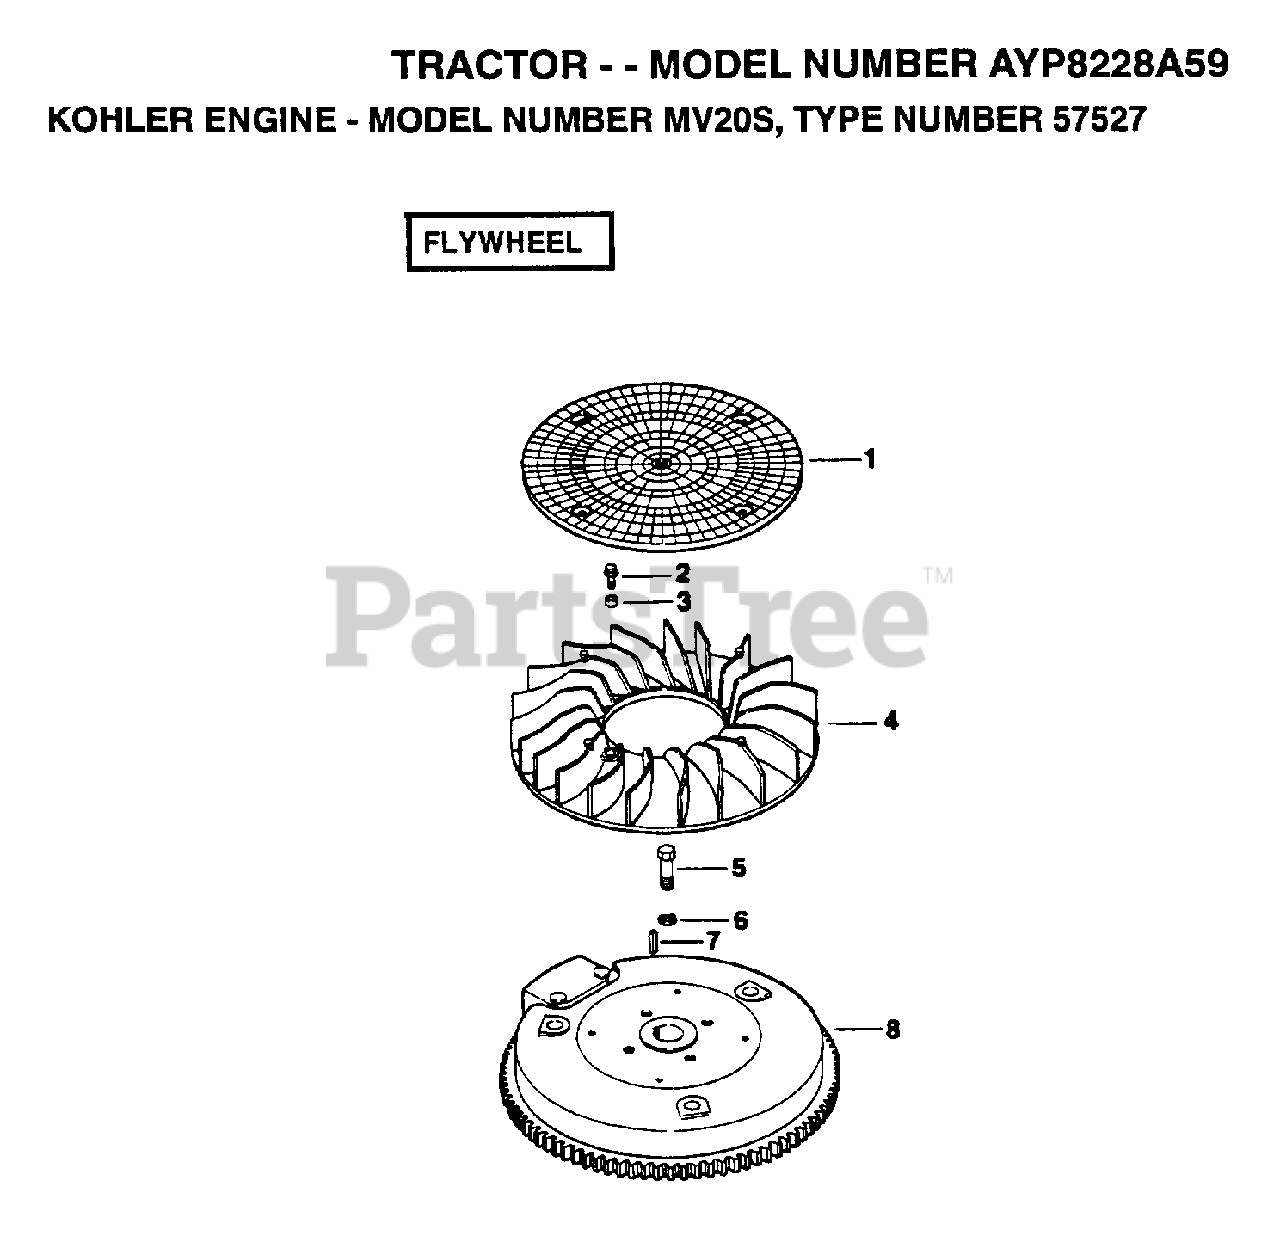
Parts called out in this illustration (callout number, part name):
2	SCREW, HEX 1/4-20 X 5/8
5	SCREW, 3/8-24X1-1/4
7	KEY
